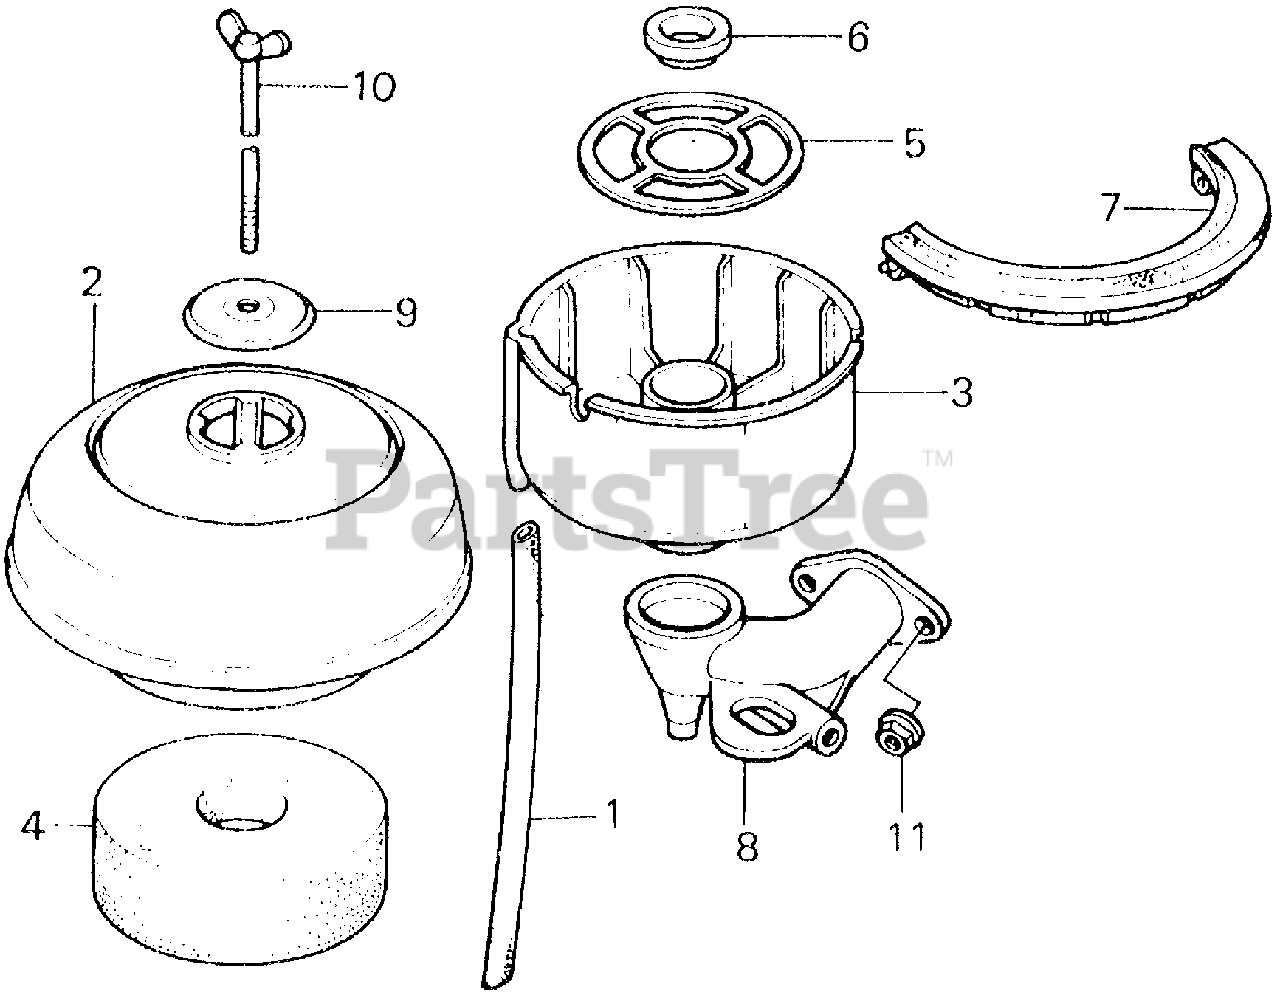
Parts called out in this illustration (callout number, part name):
1	TUBE, BREATHER
2	BODY, CLEANER
3	PAN, AIR CLEANER OIL
4	ELEMENT, AIR CLEANER
5	GRID, AIR CLEANER
6	COLLAR, AIR CLEANER (NOT AVAILABLE)
7	GASKET, OIL CLEANER
8	ELBOW, AIR CLEANER
9	CAP, AIR CLEANER
10	BOLT, AIR CLEANER
11	NUT, FLANGE (6MM)
